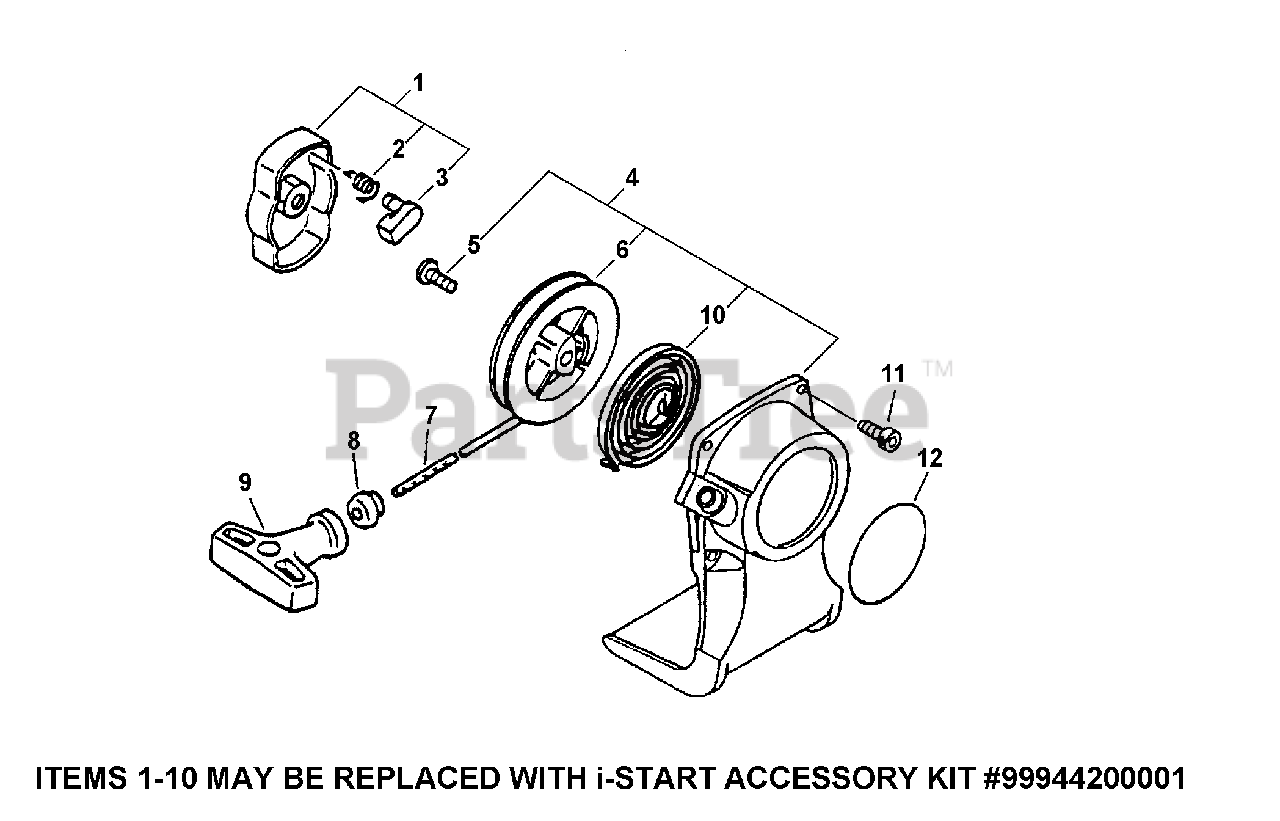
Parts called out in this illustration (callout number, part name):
1	STARTER PAWL ASSY
2	SPRING, RETURN
3	PAWL, STARTER - BLACK
4	STARTER ASSY
6	REEL, ROPE
7	ROPE, STARTER - 3X1000
8	GUIDE, ROPE
9	GRIP, STARTER
10	SPRING, REWIND
11	SCREW - 4X16
12	LABEL - ECHO
99944200001	STARTER ASSY
